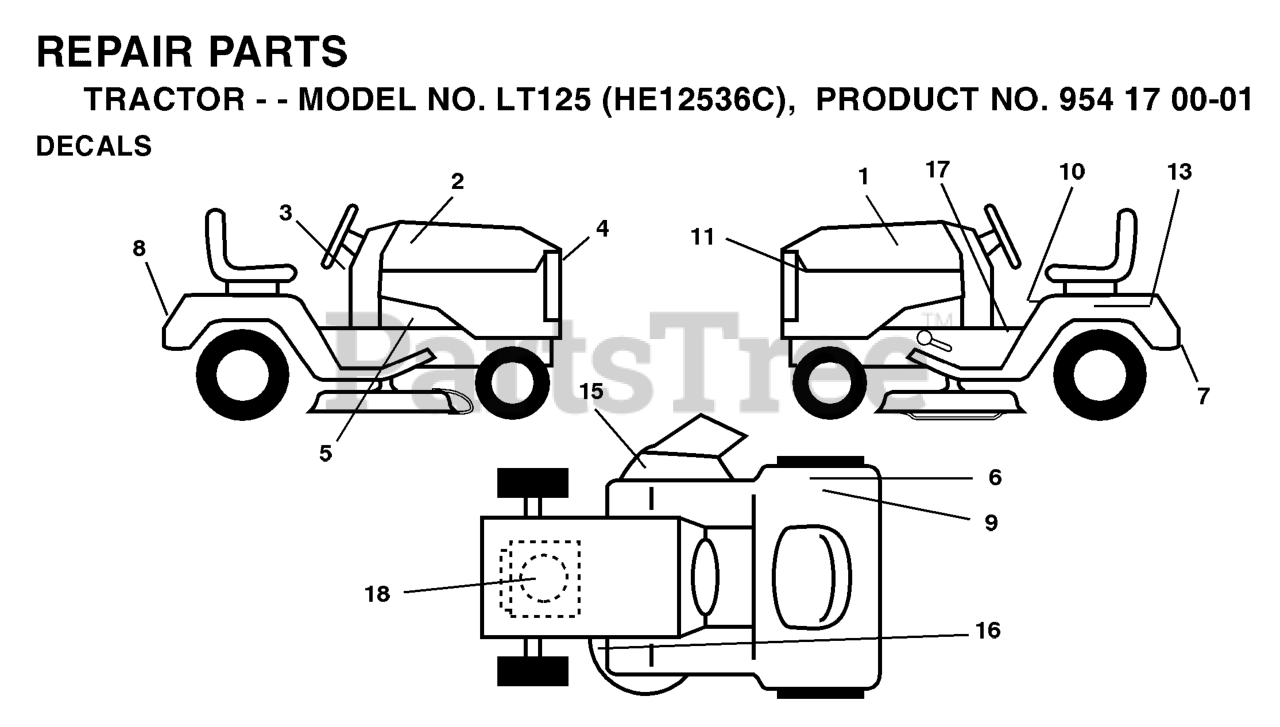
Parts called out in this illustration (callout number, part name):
4	DECAL.GRILLE.HUSQ
6	DECAL EUROPE STANDARD CE
7	DECAL
8	DECAL FENDER HUSQ
10	DECAL READ OWNER'S MAN SYMS
11	DECAL PNL SIDE
13	DECAL BTRY SYMBOLS
15	DECAL MOWER CUT/FINGER
17	Decal, Brake/Clutch Symbols
